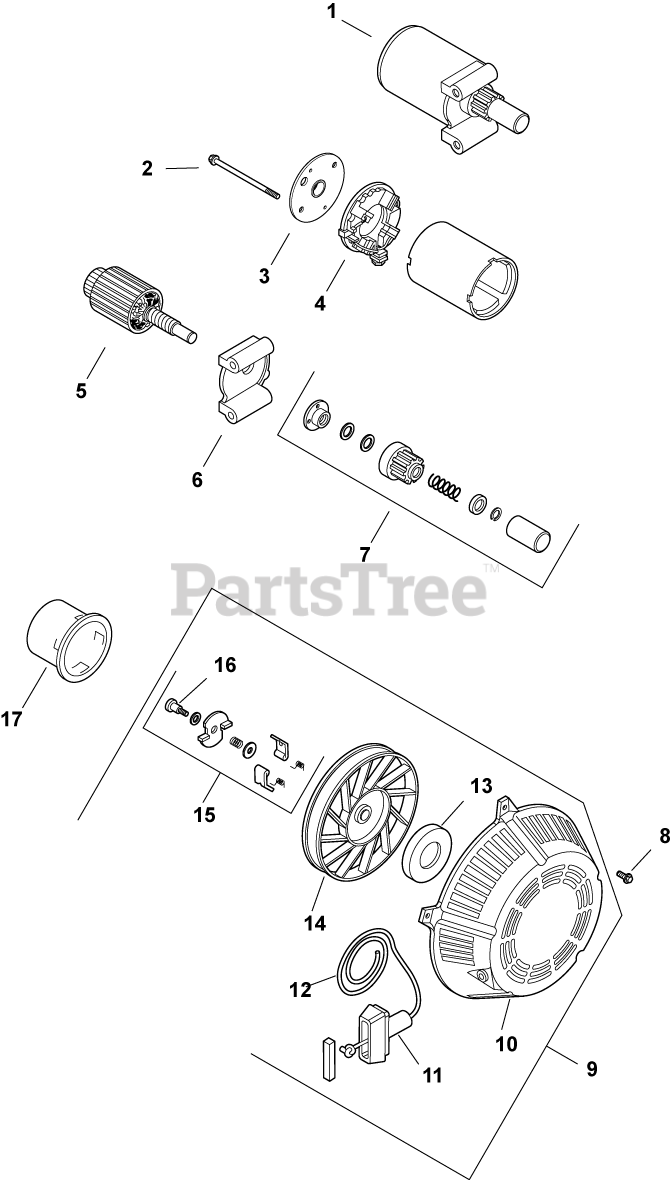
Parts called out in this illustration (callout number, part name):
1	ELECTRIC STARTER-BENDIX DRIVE
2	BOLT, THRU #10-24X4 13/32" - DISCONTINUED
3	CAP - (#DSC)
4	BRUSH KIT
5	ARMATURE - DISCONTINUED
6	CAP, DRIVE END - (#DSC)
7	KIT, DRIVE
8	SCREW, HVY FLG M5X.8X10
9	STARTER ASSY,RETRACTABLE-USE 12 165 03-S
10	HOUSING - DISCONTINUED
11	HANDLE, RECOIL STARTER
12	ROPE - DISCONTINUED
13	SPRING & KEEPER - (#DSC)
14	PULLEY - (#DSC)
15	KIT, DOG REPAIR - (#DSC)
16	SCREW - DISCONTINUED
2511325-S	DECAL, MEDIUM ROUND
